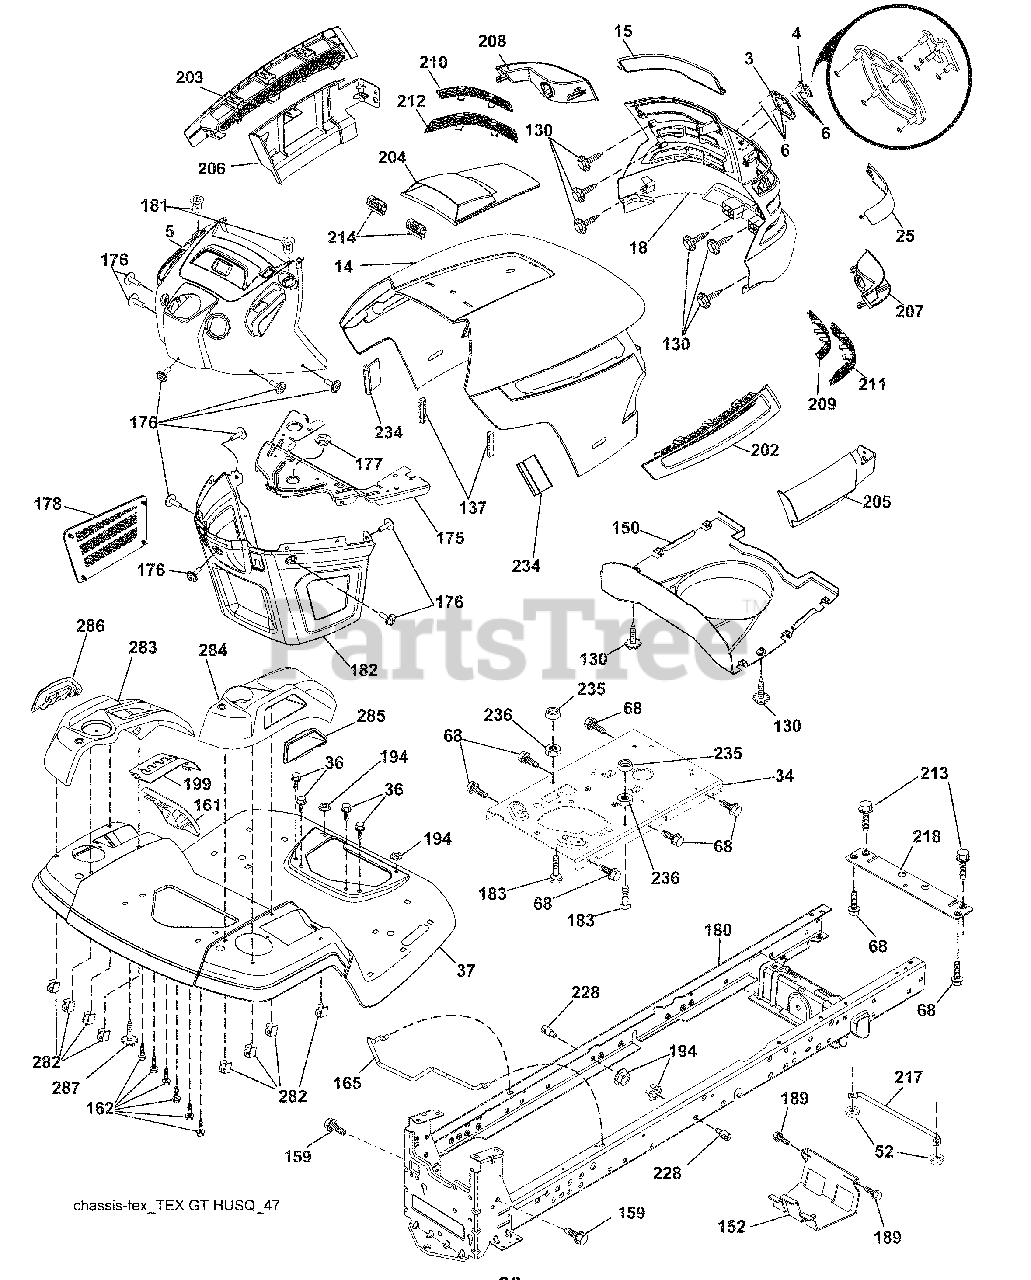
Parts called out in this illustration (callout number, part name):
3	Trim, Husq.
4	Logo
5	Dash
14	Hood
18	Grille/Lens Asm.
34	Plate Engine
36	Screw 5/16-18 x 3/4
52	Nut Lock 5/16-18
68	Screw Thdrol 5/16-18 x 1/2
130	Screw 10 x 0.750 BOS Thread
137	Bumper Dash
152	Shield Browning
159	Screw 3/8-16 x 3/4
161	Window Fuel
162	Screw Hex Wsh Hi-Lo 1/4 x 1/2 unc
165	Support Tank Rear
175	Crossmember
176	Screw 10-24 x 5/8
177	Bushing Steering
178	Cargo Net Asm.
180	Chassis
181	Bushing Mtg. Fender Crgo
182	Dash Lower
183	Bolt Fin Hex 5/16-18 unc x 1-1/4
189	Screw 5/16-18 x 3/4
194	Nut Lock Hex Flange 5/16-18
199	Plate Deck Lift
202	Vent Side Hood RH
203	Vent Side Hood LH
204	Vent Top Hood
205	Skirt Hood Side RH
206	Skirt Hood Side LH
209	Insert Hex Top RH
210	Insert Hex Top LH
211	Insert Hex Bottom RH
212	Insert Hex Bottom LH
213	Bolt 5/16-18 x 3/4
214	Clip Retainer Tinner
218	X-Piece Hood Stop
228	Stud Fastener
234	Bumper Hood
235	Spacer Fender
236	Nut Lock 5/16-18 unc
282	Clip Retainer Console
283	Console Deck Lift
284	Console Shift
285	Console Insert RH
286	Console Insert LH
287	Screw 1/4-20 X 3/8
